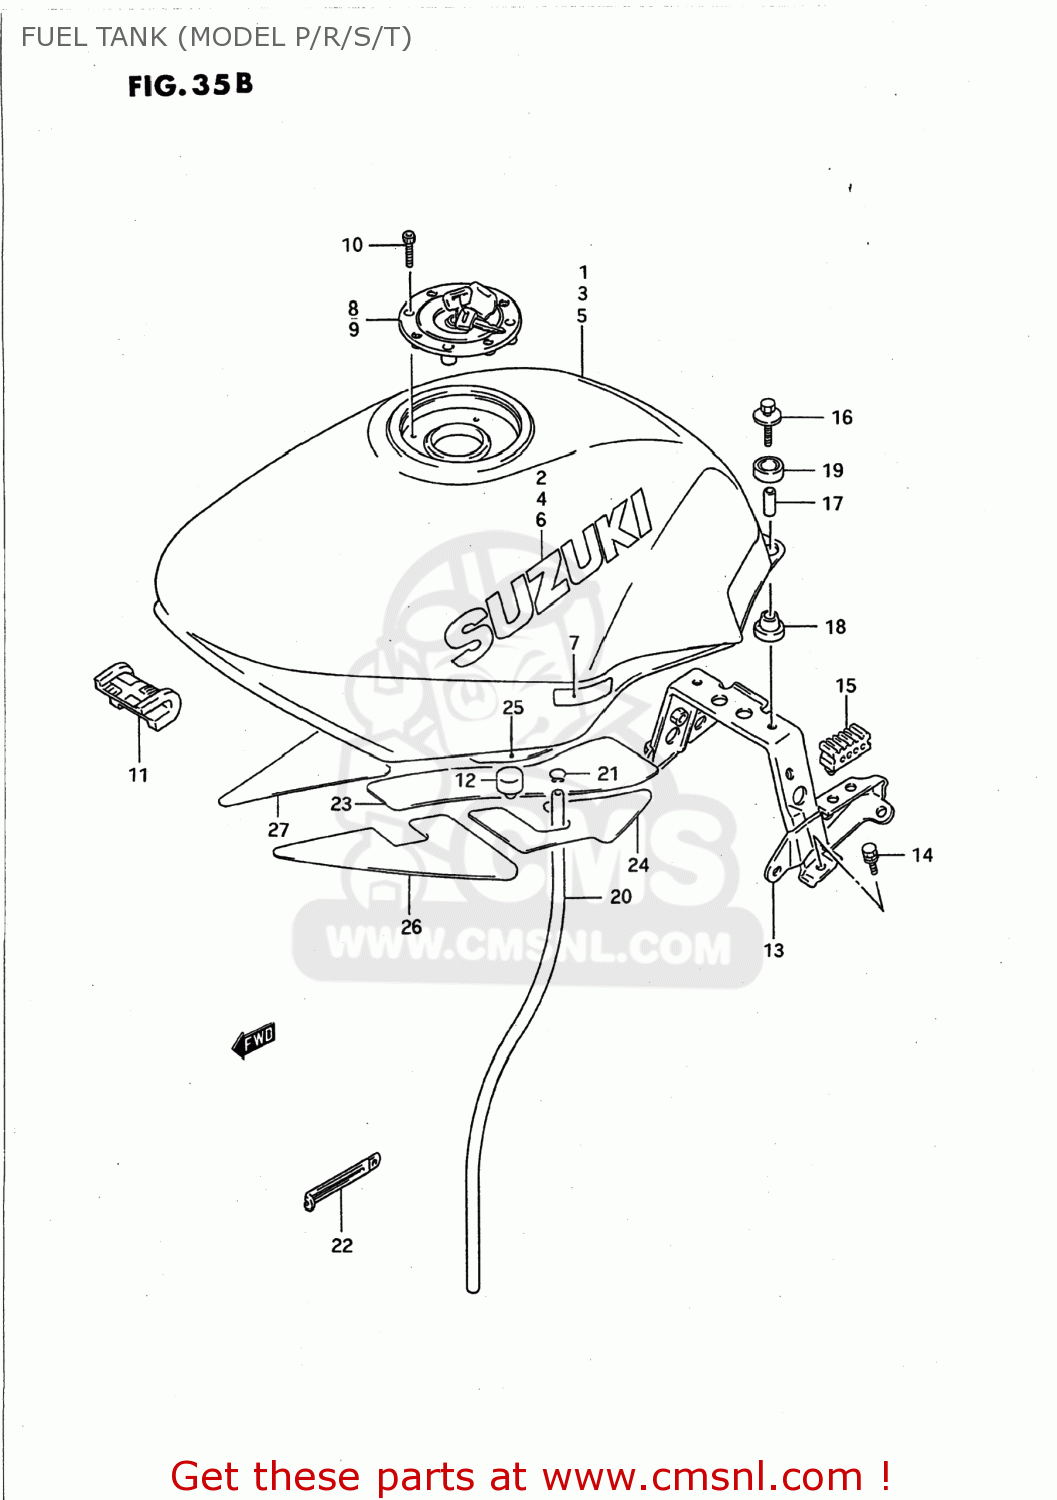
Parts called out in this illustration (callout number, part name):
1	TANK ASSEMBLY,FUEL
2	EMBLEM,FUEL TANK
3	TANK ASSEMBLY,FUEL
4	EMBLEM
5	TANK ASSEMBLY,FUEL
6	EMBLEM,FUEL TANK
7	PROTECTOR(12X40)
8	CAP SET,FUEL TANK
9	CAP SET,FUEL
10	BOLT(5X20)
11	CUSHION,FUEL TANK FR
12	CUSHION
13	BRACKET,FUEL TANK RR
14	SCREW
15	CUSHION,SEAT(40X20X15)
16	BOLT
17	SPACER
18	CUSHION
19	CUSHION
20	HOSE,FUEL TANK WATER DRAIN
21	CLIP
22	CLAMP(L:120 T:1.0)
23	HEATSHIELD,CTR
24	HEATSHIELD,RR,L
25	HEATSHIELD,RR,R
26	HEATSHIELD,FR,L
27	HEATSHIELD,FR,R
